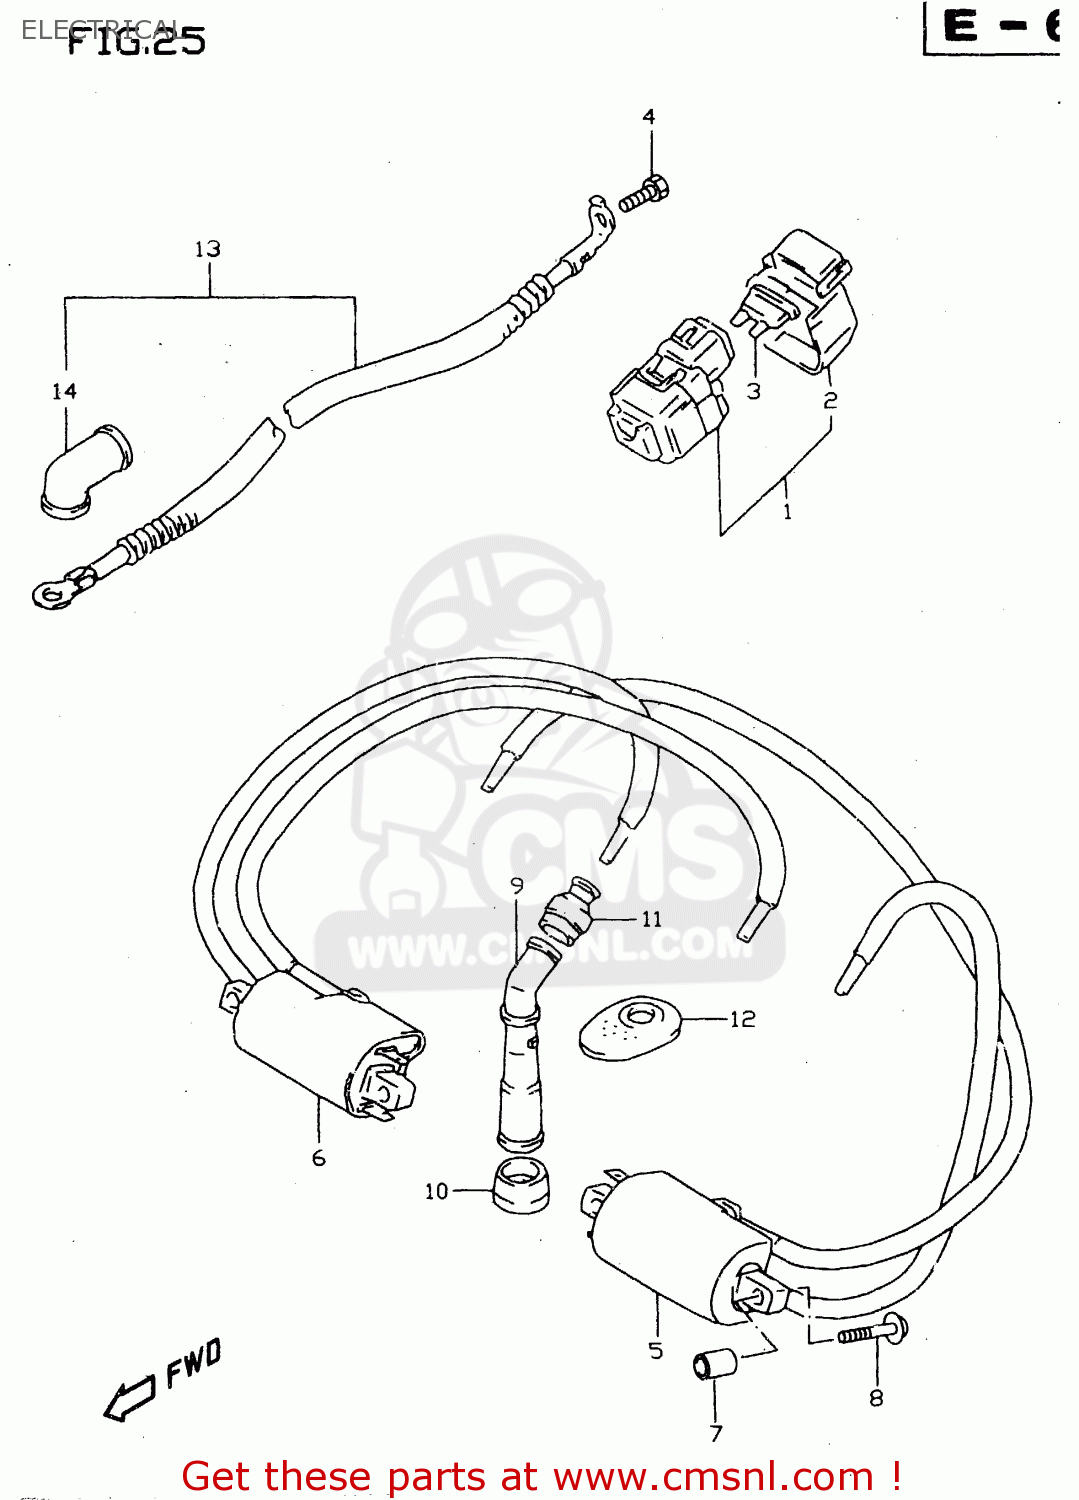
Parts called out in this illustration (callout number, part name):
1	RELAY ASSY,STARTING MOTOR
2	COVER,RELAY ASSEMBLY
3	FUSE(30A)
4	SCREW(6X8)
5	COIL ASSY,IGNITION
6	COIL ASSY,IGNITION
7	SPACER(6.2X12X5)
8	BOLT
9	CAP,SPARK PLUG
10	SEAL,SPARK PLUG CAP
11	SEAL,HIGH TENSION CORD
12	COVER,SPARK PLUG CAP
13	WIRE,STARTER MOTOR LEAD
14	CAP,STARTER MOTOR LEAD
